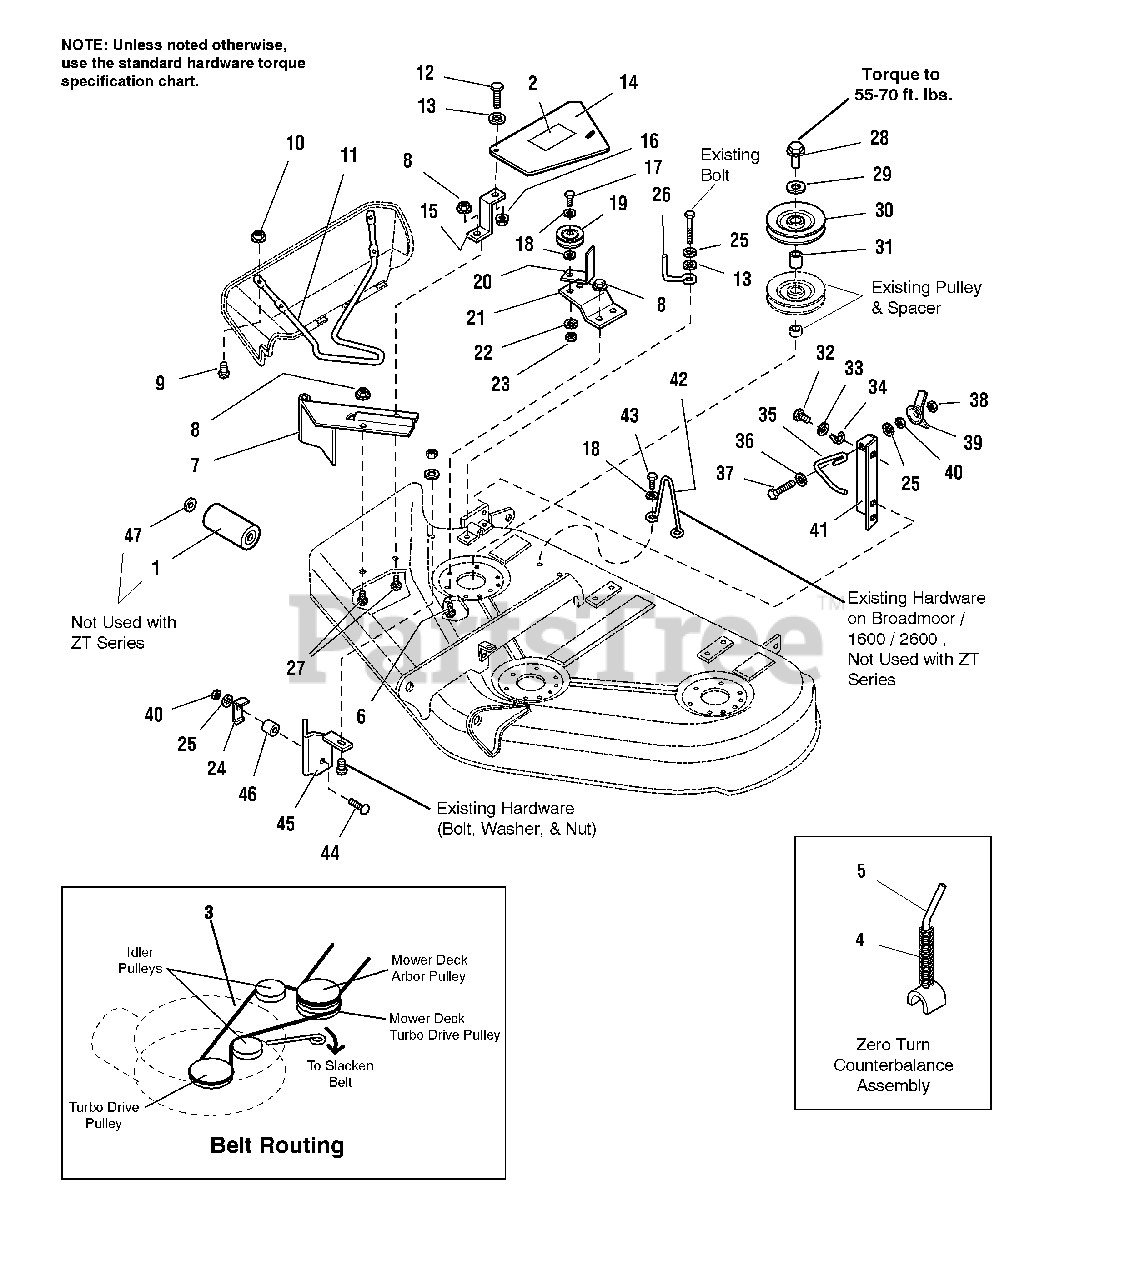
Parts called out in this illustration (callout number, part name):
2	DECAL, Warning
3	V-BELT
4	SPRING, Counterbalance
5	LEVER ASSY, Counterbalance
6	CAPSCREW, Hex Hd, 5/16-18 x 7/8
7	PIVOT ASSEMBLY
8	NUT, Hex Whizlock, 5/16-18
9	SCREW, Truss Hd, #10-24 x 3/4
10	NUT, Hex, Nylon Lock, #10-24
11	ROD, Deflector
12	CAPSCREW, Hex Hd, 5/16-18 x 1
13	WASHER, 5/16
14	COVER, Belt
15	SUPPORT, Belt Cover
16	NUT, Hex 5/16-18
17	CAPSCREW, Hex Hd 3/8-16 x 1-1/2
18	WASHER, Flat, 3/8
19	PULLEY ASSEMBLY, Idler
20	LATCH, Belt Cover
21	BRACKET, Idler
22	LOCKWASHER, 3/8
23	NUT, Hex, 3/8-16
25	LOCKWASHER, 5/16
27	CARRIAGE BOLT, 5/16-18 x 1
28	NUT, Sleeve
29	WASHER, Belleville
31	HUB, Double Pulley, 1.16" Long
32	CAPSCREW, Hex Hd, 1/4-20 x 1/2
33	WASHER, 1/4
34	BELT STOP, (Height Indicator)
35	LATCH, Spring
36	WASHER, 5/16
37	CAPSCREW, Hex Hd, 5/16-18
38	NUT, Hex Lock, 5/16-18
39	NUT, Wing, 5/16
40	NUT, Hex, 5/16-18
41	BRACKET, Anchor
42	UPSTOP, Wire
43	CAPSCREW, Hex Washer Hd, Taptite, 5/16
44	CARRIAGE BOLT, 5/16-18
45	BRACKET ASSEMBLY, Cutoff
47	PUSHNUT
